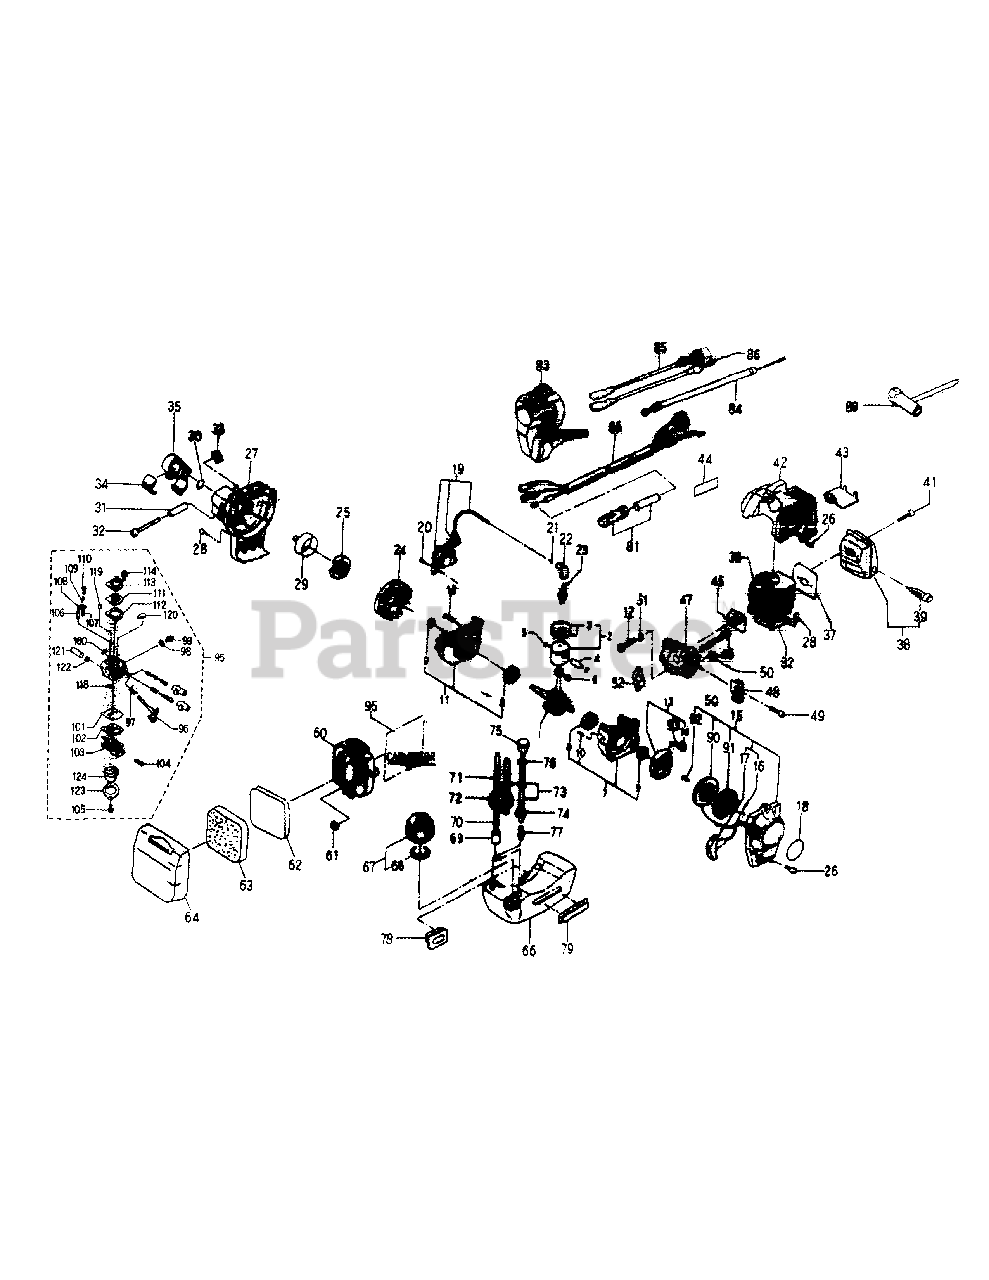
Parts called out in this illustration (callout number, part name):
1	Crankshaft
2	Piston Assembly
3	Ring, Piston
4	Pin, Piston
5	Clip, Piston Pin
6	Needle Bearing
7	Crankcase Assembly
8	Ball Bearing:6201
9	Oil Seal
10	Dowel Pin
11	Crankcase Assembly
12	Bolt: M5x25
13	Pulley Assembly, Starter
15	Recoil Assembly
16	Rope, Starter
17	Knob, Starter
18	Name Plate
19	Coil Assembly, Ignition
20	Bolt: M4x20
22	Cap, Plug
23	Spark Plug
24	Flywheel, Magneto
25	Clutch Assembly
26	Bolt; M5 x 20
27	Housing Blower
28	Bolt; M5 x 16
29	Drum, Clutch
30	Snap Ring
32	Bolt; M5 x 30
36	Cylinder
37	Gasket, Muffler
39	Arrester
41	Bolt; M5 x 48
42	Cowling, Cylinder
43	Baffle Plate
44	Trade Mark
45	Gasket, Insulator
46	Bolt; M5 x 56
47	Insulator
48	Adjuster
49	Bolt; M5 x 12
51	Washer
60	Case, Air Silencer
62	Element (B), Filter Air
63	Element (A), Filter Air
64	Case, Cap
65	Wire complete, Throttle
66	Tank, Fuel
67	Cap Assembly, Fuel Tank
69	Filter, Fuel
71	Hose
73	Hose
75	Valve Assembly, reversing
77	Connector
79	Rubber
81	Holder, Wire
83	Lever assembly, Throttle
84	Wire, Throttle
85	Harness, Wire
86	Harness, Wire
91	Spring, Spiral
93	Spring, Return
95	Carburetor Assembly
96	Shaft, throttle
98	Valve, Throttle
101	Diaphragm, Pump
103	Base Assembly, Primer
106	Valve, Float
108	Arm, Float
109	Pin, Float
111	Diaphragm, Metering
113	Cover
119	Nozzle, Capsule
120	Blank Plug
121	Seat Assembly, Valve
